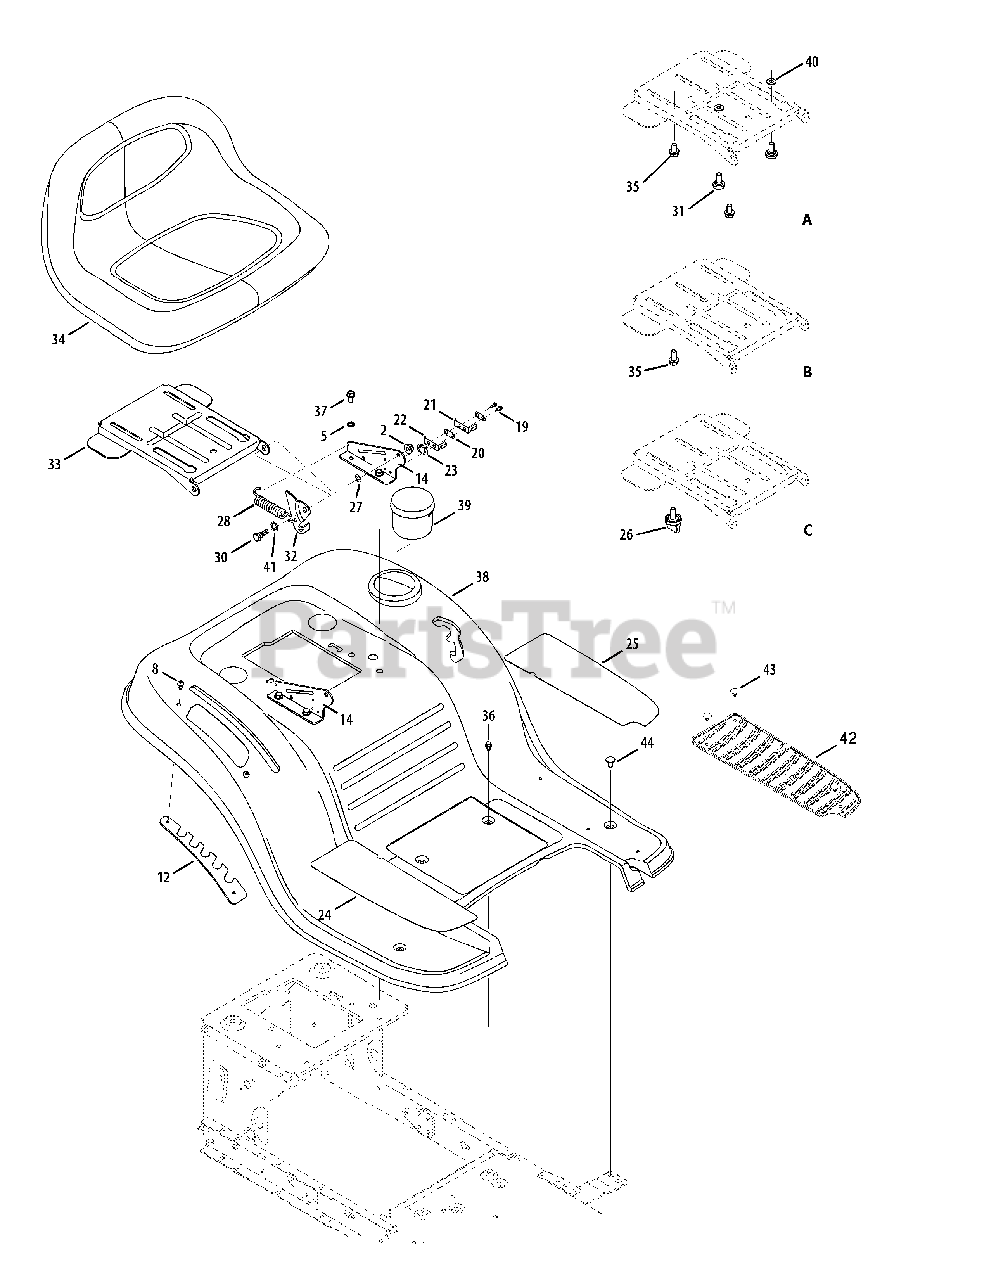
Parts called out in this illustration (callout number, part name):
2	Flange Locknut 5/16-18 Gr. F, Nylon
5	Lockwasher 5/16 ID
8	Screw, 1/4-20 x .50
12	Lift Adjustment Bracket
14	Seat Mounting Bracket
19	Hex Wash HD AB S-Tapp Scr #8-.50
20	Insulator Plate
21	Spring Switch
22	Seat Spring Switch
23	Insulator Plate
24	Foot Pad, Abrasive, RH
25	Foot Pad, Abrasive, LH
27	Push Speed Nut
28	Extension Spring .84 Dia. x 4.6
30	Shoulder Screw
31	Shoulder Screw .625 x .175, 3/8-16
32	Seat Lift Bracket
33	Seat Pivot Bracket
34	Seat, Low Back
35	Screw 3/8-16 x .875
36	Hex Wash S-Tapp Scr 1/4-20 x .50
37	S-Tapp Scr 5/16-18 x .75
38	Fender
40	Flat Washer .405 x .875 x .059
40	Flat Washer .395 x .62 x .063
41	Flat Washer .510 x .750 x .033
44	Carriage Bolt 1/4-20 x .62
